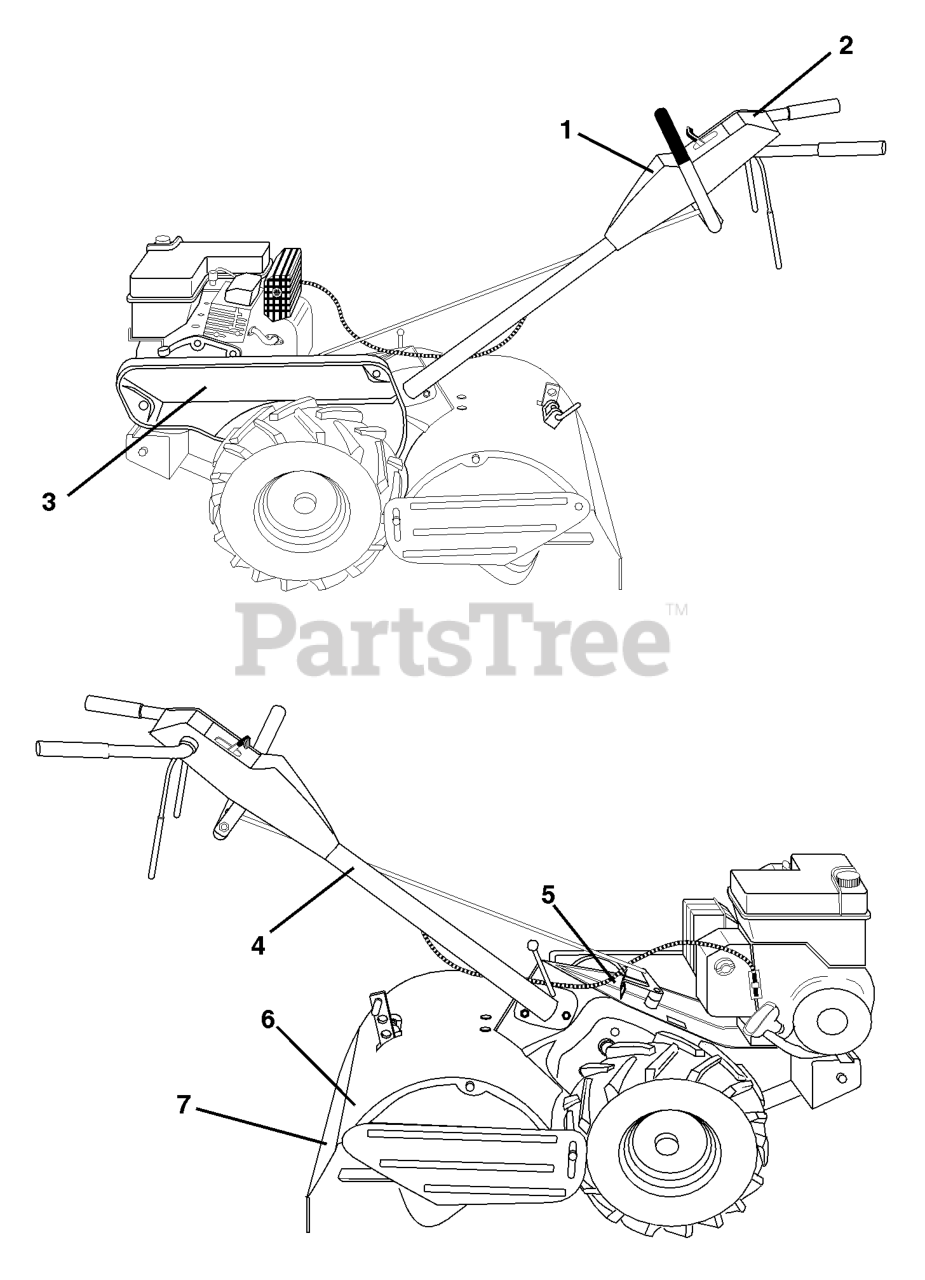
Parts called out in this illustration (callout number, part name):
1	DECAL, LOGO
2	DECAL, LOGO
3	LOGO DECAL CRT61
4	DECAL TI (2 2)
5	DECAL TI NLA
7	DECAL TI
